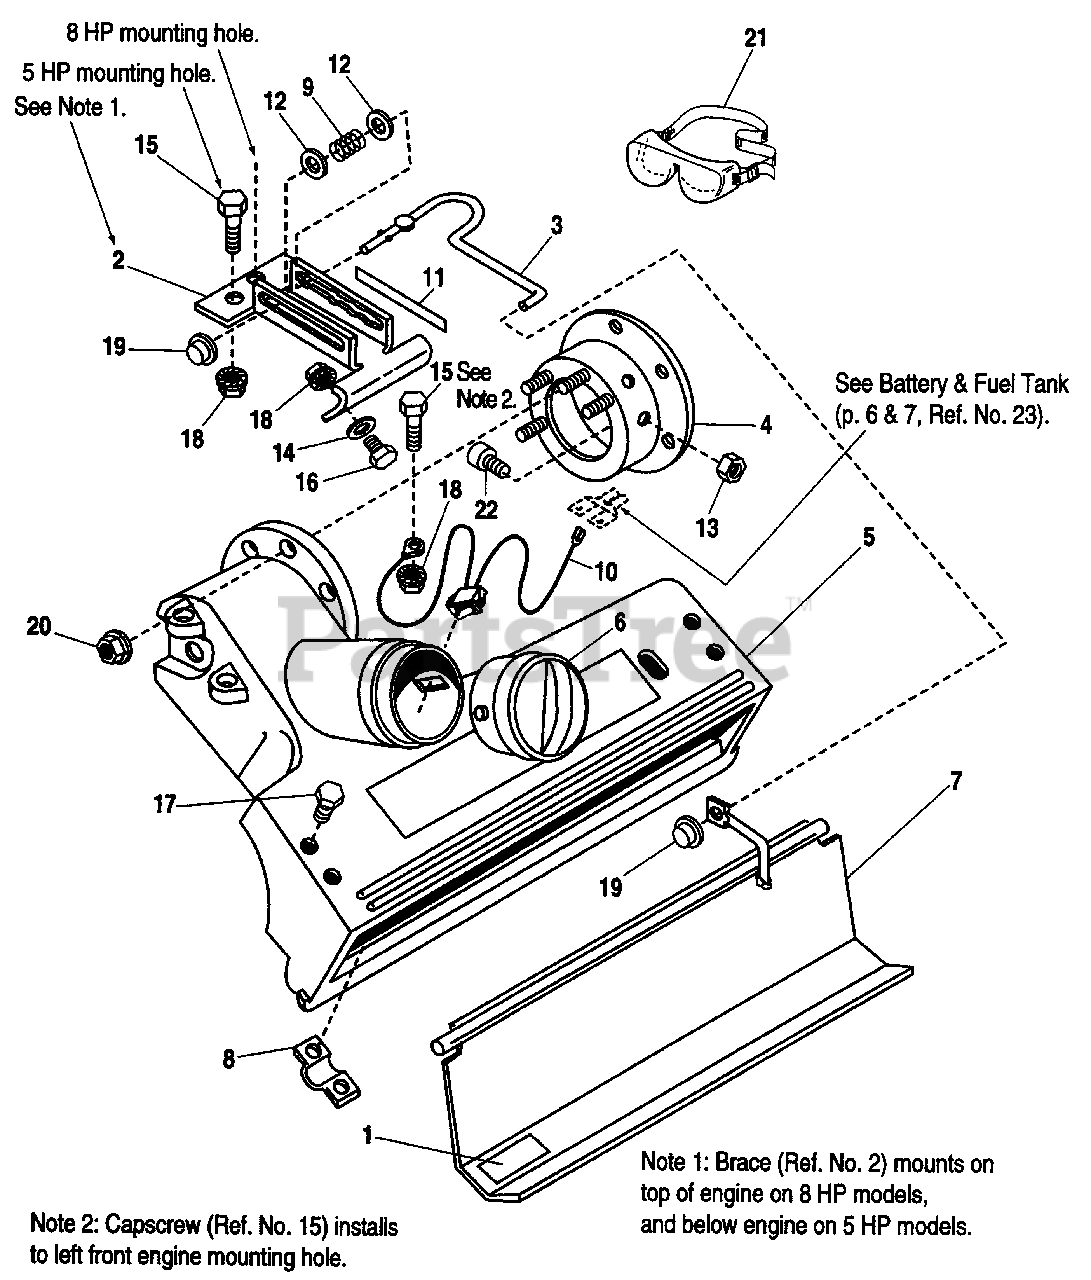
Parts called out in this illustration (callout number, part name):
1	DECAL, Danger
4	SHREDDER HOUSING ASSY.
5	NOZZLE, (Simplicity)
5	NOZZLE, (Baker)
6	PLUG, Nozzle
8	CLAMP, Shaft
10	SWITCH, Interlock N.C.
11	DECAL, Nozzle Opening
12	WASHER, 5/16
13	NUT, Nylock, 5/16-18
14	WASHER, 5/16
15	CAPSCREW, Hex Hd., 5/16-18 x 1/2
16	CAPSCREW, Hex, Hd., 5/16-18 x 3/4
17	SCREW, Taptite, #10-32 x 3/8
18	NUT, Serrated, Flange Lock, 5/16-18
19	PUSH NUT, 5/16
20	NUT, Hex, Flange Lock, 5/16-18
22	CAPSCREW, Hex, Socket Hd., 5/16-18 x 1/2
